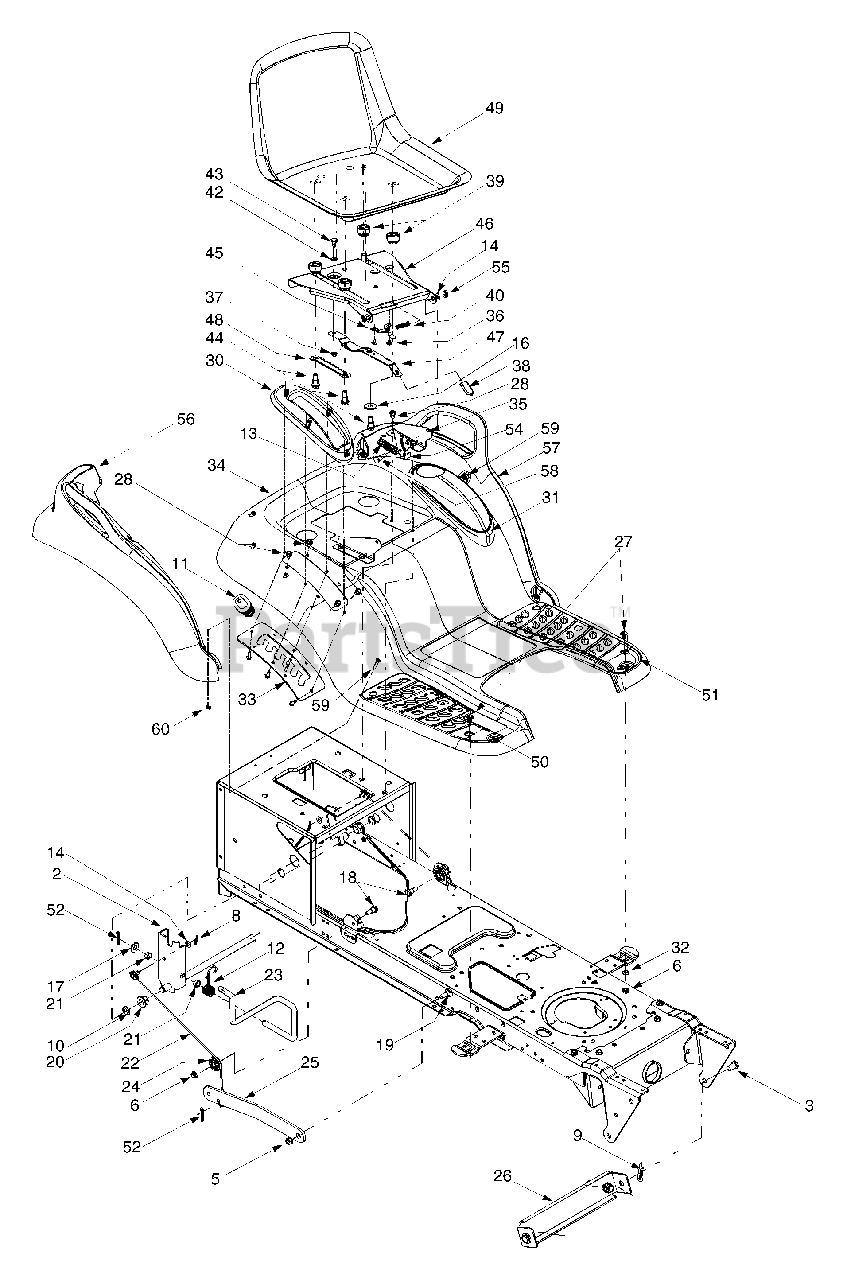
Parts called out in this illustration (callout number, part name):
2	Lift Shaft Assembly Service Kit
3	Clevis Pin,.5 x.78
4	Hex Nut, 1/2-13
5	Flange Lock Nut, 3/8-16
6	Flange Lock Nut, 5/16-18
8	Hairpin Clip
12	Torsion Spring
13	Extension Spring,.84 x 4.6
14	Flat Washer, 5/16
16	Flat Washer,.31 x 1.062 x.134
17	Flat Washer,.51 x 1.12 x.06
18	Hex Cap Screw, 5/16-18 x.62
19	Shoulder Screw, 3/8-16
20	Hex Flange Bearing
21	Snap Flange Bearing
22	Lift Cable, 16.16
24	Roller Pulley
27	Carriage Bolt, 5/16 x.62
28	Self-tapping Screw, 5/16-18 x.625
29	Self-tapping Screw, 1/4-15 x.75
30	Lift Lever Cover
31	Cover w/ Cup Holder
32	Flat Washer,.349 x 1.0 x.063
36	Screw, #10-16 x.375
37	Hex Flange Lock Nut, 1/4-20
38	Seat Adjuster Grip
40	Compression Spring,.41 x 1.5
42	Flat Washer,.344 x.62 x.03
43	Shoulder Screw,.340 x.285,1/4-20
44	Shoulder Screw,.50 x.50, 3/8-16
48	Seat Adjustment Selector
49	High Back Seat, Black
54	Seat Lift Bracket
56	RH Fender Flare
57	LH Fender Flare
58	Shoulder Screw,.437 x.286
59	Carriage Screw 1/4-20 x 1.00
60	Sems Nut 1/4-20
